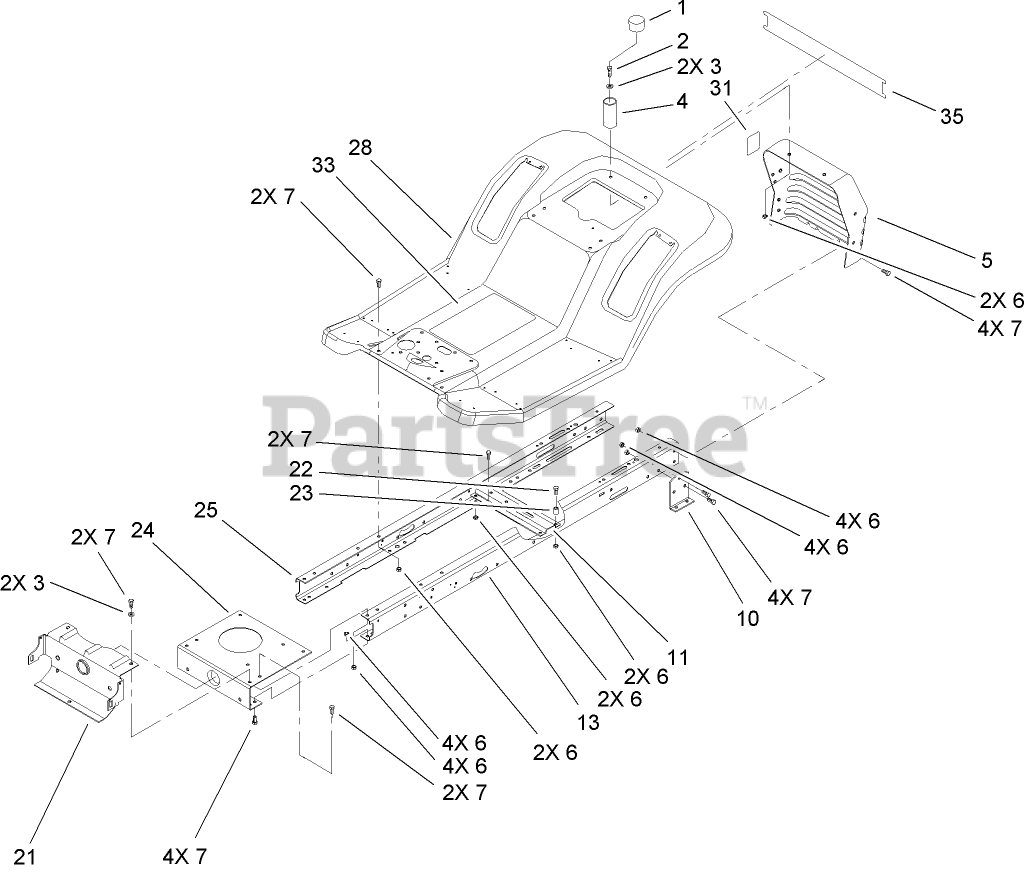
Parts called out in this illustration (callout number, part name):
1	CAP-PROTECTOR
2	SCREW-HH
3	WASHER-PLAIN
4	SPRING-COMPRESSION
5	SUPPORT-SEAT/REAR HITCH
6	NUT-LOCK, NI
7	SCREW-HH
10	BRACKET-TRANSAXLE, MOUNTING
11	BRACKET-IDLER PIVOT
13	RAIL-FRAME, LH
21	SUPPORT-AXLE, FRONT
22	SCREW-HH
23	SPACER
24	PLATE-MOUNTING, ENGINE
25	RAIL-FRAME, RH
28	REAR BODY ASM
31	DECAL-VALVE, DUMP
33	DECAL-INSTRUCTION
35	DECAL-REAR FENDER, LAWN TRACTORS
